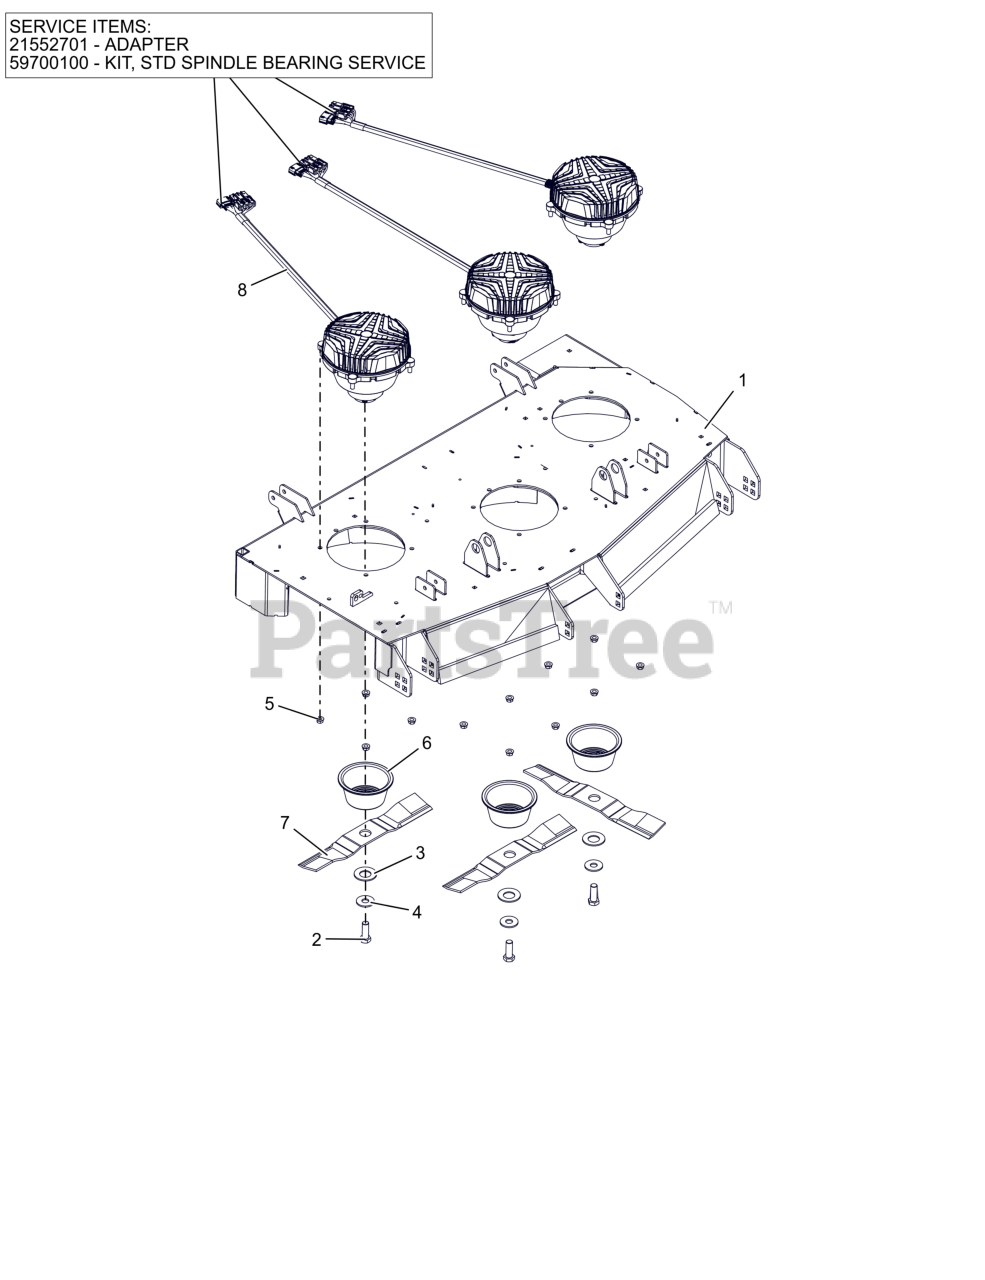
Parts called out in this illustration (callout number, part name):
1	WLDMT-48" PSEV SIDE DISCH DECK
2	BLT, HEX .62-18X1.75 G8 ZCC
3	WSHR, BLVL - .56X28.5X3 PHOS.COAT
4	WSHR, HRDN 0.687X1.75X0.134 HRD
5	NUT-LK-CTR-FLG .375-16 GF ZCC
6	GUARD, SPINDLE LOWER
7	BLADE, MOWER -16.190" EFF CW
8	MOTOR, DECK - 48"/52" CW
8	ADAPTER
8	KIT, STD SPINDLE BEARING SERVICE
